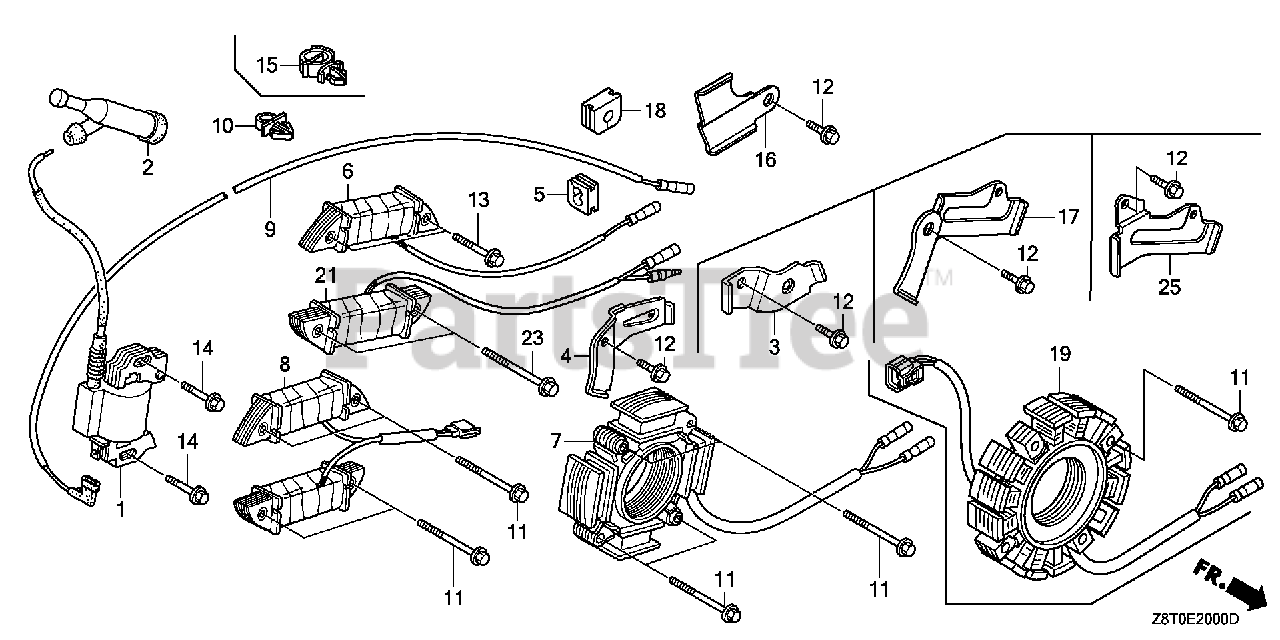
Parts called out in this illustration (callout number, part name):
1	COIL ASSY., IGNITION
2	CAP ASSY., NOISE SUPPRESSOR (NGK Y-EZD)
4	CLAMP, WIRE
5	GROMMET, WIRE
6	COIL ASSY., CHARGE (1A)
12	BOLT, FLANGE (6X12) (CT200)
13	BOLT, FLANGE (6X35)
14	BOLT, FLANGE (6X28) (CT200) Use up to Engine SN 1530314.
